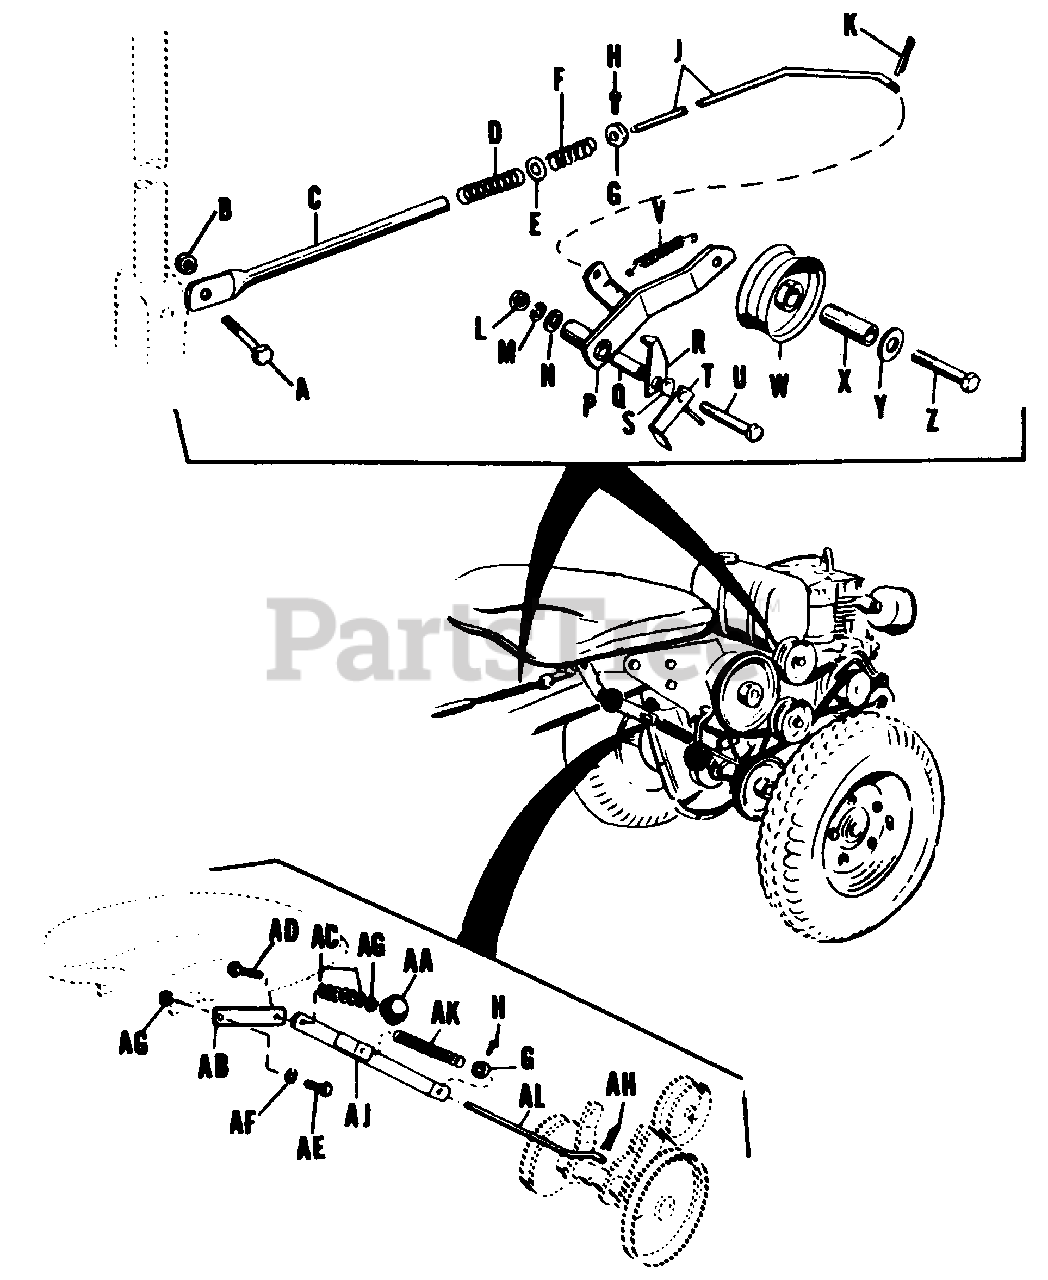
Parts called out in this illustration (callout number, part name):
A	Capscrew, Hex Hd., 5/16-18 x 3/4
B	Nut, Lock, Full Hex, 5/16-18
C	Rod, Front Clutch Assembly
E	Washer, Plated, 5/16
G	Collar, Set
H	Set Screw, Sq. Hd., 1/4-20 x 3/8
J	Rod, Rear Clutch
K	Pin, Cotter, 3/32 x 5/8
L	Nut, Full Hex, 3/8-16
M	Washer, Lock, 3/8
N	Washer, Plain, 3/8
P	Lever Assembly, Idler
R	Stop, Lever
S	Pin, Lock
T	Guide, Belt
U	Capscrew, Hex Hd., 3/8-16 x 3
W	Pulley, Idler
X	Race, Inner Bearing
Y	Washer, Plain, 3/8
Z	Capscrew, Hex Hd., 3/8-16 x 2
AC	Washer, Plain, 3/8
AD	Screw, Hex Hd. Cap, 3/8-16 x 1 3/4
AE	Screw, Hex Hd. Cap, 3/8-16 x 1 1/2
AF	Washer, Plain, 3/8
AG	Hex Nut, Full Lock, 3/8-16
AH	Pin, Cotter, 3/32 x 5/8
AJ	Guide Assembly
AL	Rod, Clutch
